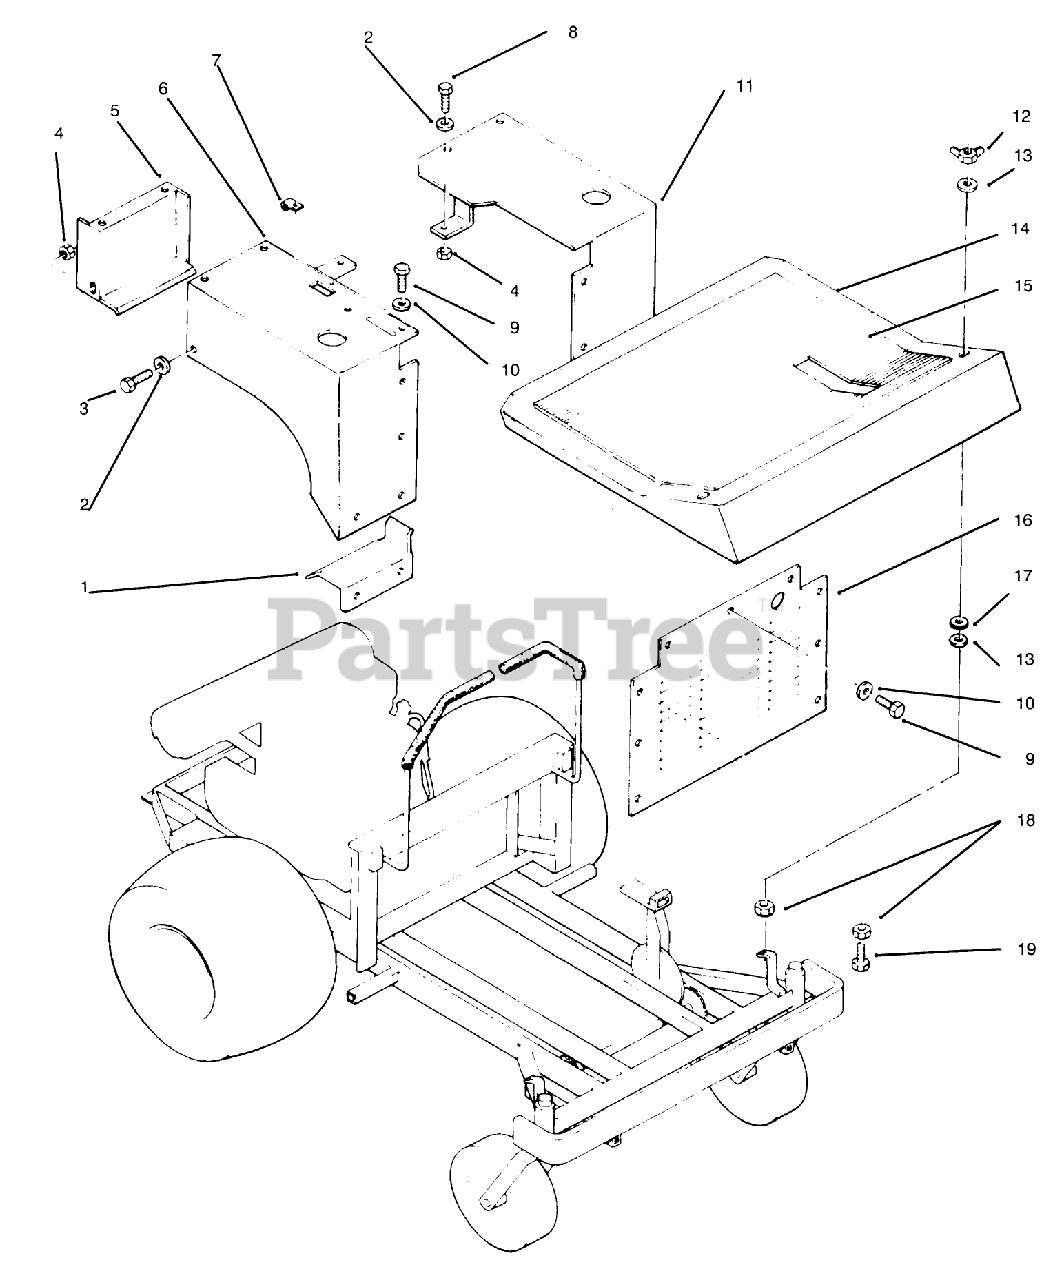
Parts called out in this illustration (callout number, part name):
1	Bracket-Fender Frt RH
2	WASHER-FLAT
3	SCREW-HH
4	NUT-LOCK, NI
5	Bracket-Fender Rear RH
6	FENDER WA RH R
7	J-CLIP
8	SCREW-HH
9	SCREW-HWH
10	WASHER-FLAT
11	Fender LH
12	WING NUT
13	WASHER-FLAT
14	Floor Pan
15	MAT - FOOTREST
16	Front Panel
17	WASHER
18	NUT-HEX
19	SCREW-HH
